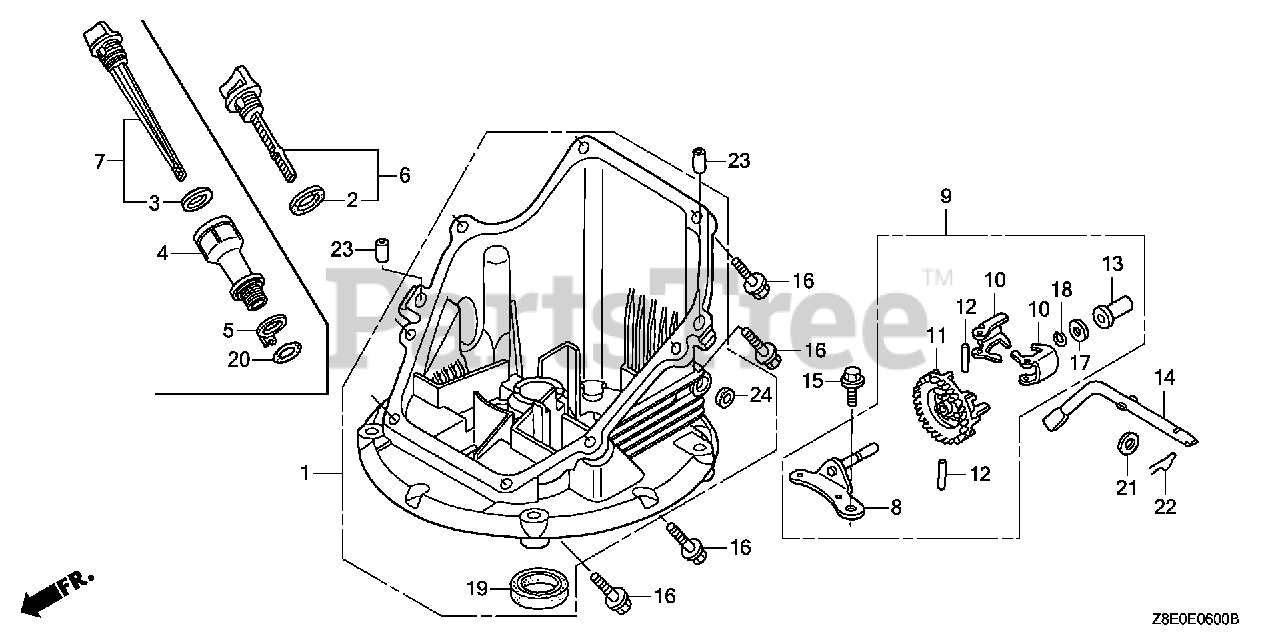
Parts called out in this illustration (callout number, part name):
1	PAN ASSY., OIL
2	GASKET, OIL FILLER CAP (NOT AVAILABLE)
6	GAUGE ASSY., OIL LEVEL
8	SHAFT, GOVERNOR HOLDER
9	GOVERNOR ASSY.
10	WEIGHT, GOVERNOR
11	HOLDER, GOVERNOR WEIGHT
12	PIN, GOVERNOR WEIGHT
13	SLIDER, GOVERNOR
14	SHAFT, GOVERNOR ARM
15	BOLT, FLANGE (6X14)
16	BOLT, FLANGE (6X25) Use up to Engine SN 2056819.
17	WASHER, THRUST (6MM)
18	CLIP, GOVERNOR HOLDER
19	OIL SEAL (28X41.25X6)
21	WASHER, PLAIN (6MM)
22	PIN, LOCK (8MM)
23	PIN, DOWEL (8X20)
24	OIL SEAL (6X11X4)
